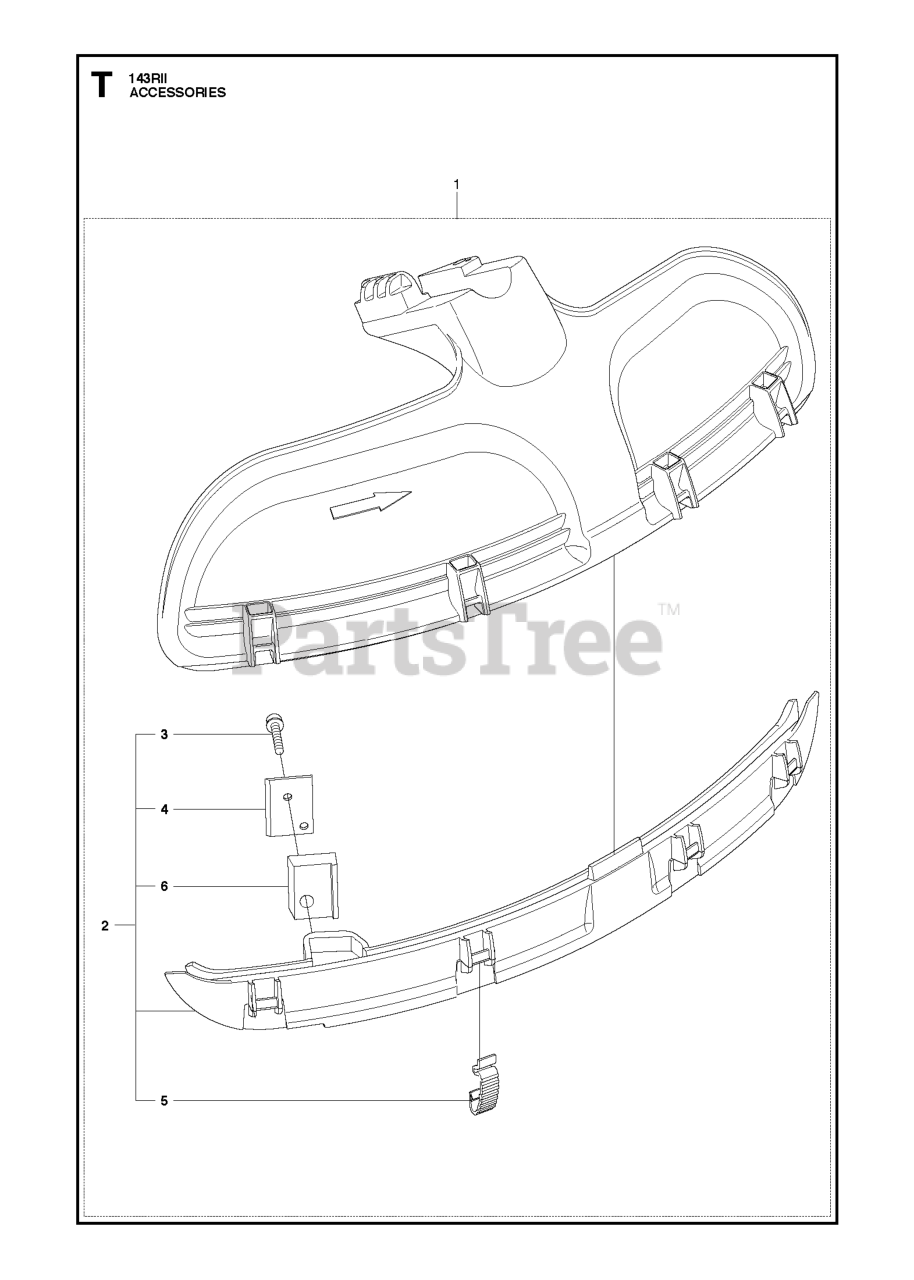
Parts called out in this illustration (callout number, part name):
1	COMBI PROTECTOR
2	SPLASH GUARD
4	LINE CUTTER
6	DISTANSBLOCK
